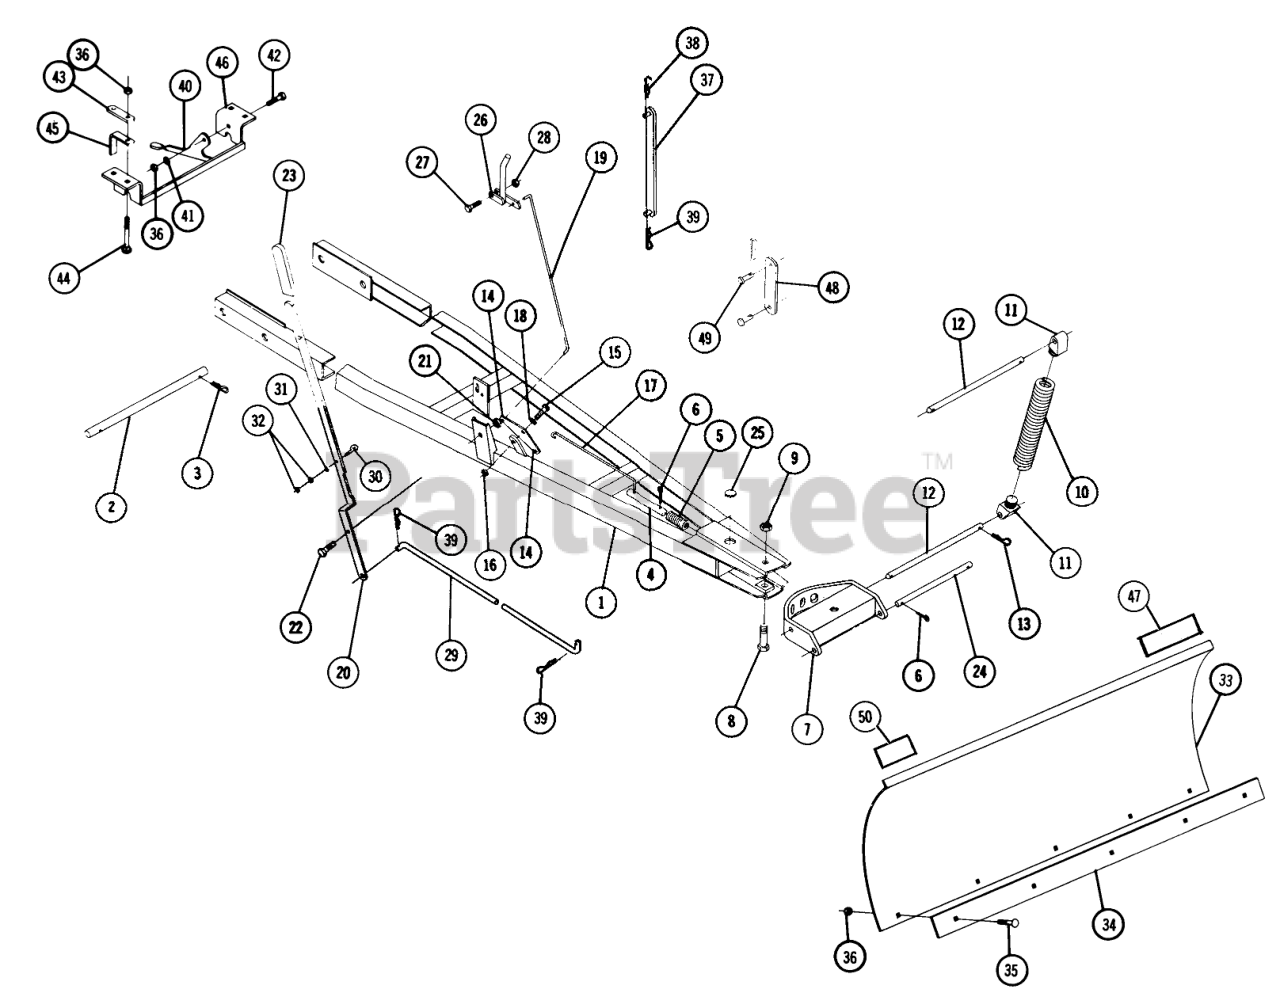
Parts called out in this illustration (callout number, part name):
1	Ass-y. Frame
2	Mounting Shaft
3	Hairpin
4	Index Pin
5	SPRING-COMPRESSION
7	Sector and Channel
8	Bolt
9	Nut
10	Spring
11	Lug
12	ROD-PIVOT, BLADE
13	Hairpin
14	Index Plate
15	BOLT
16	NUT
17	Head-Cylinder
18	Washer
19	UPPER INDEX ROD
20	Index Lever
21	Jam Nut
22	Bolt
23	GRIP
24	ROD-LOWER
25	PLUG
26	INDEX LEVER
27	Bolt
28	Nut
30	Eye Bolt
31	Lockwasher
32	Nut, #10-24 Hex
33	Blade
34	Plate
35	Bolt-Carriage
36	NUT
37	LIFT BAR ASSY R
38	Hairpin Cotter
39	Hairpin
40	PLATE-LATCHING
41	Washer
42	BOLT
43	BRACKET-REAR LINK MOUNTING
44	Bolt-Carriage
45	SPACER-BRACKET
46	Bracket
47	DECAL-WHEEL HORSE
48	LINK-LIFT
49	Pin
50	Caution Decal
